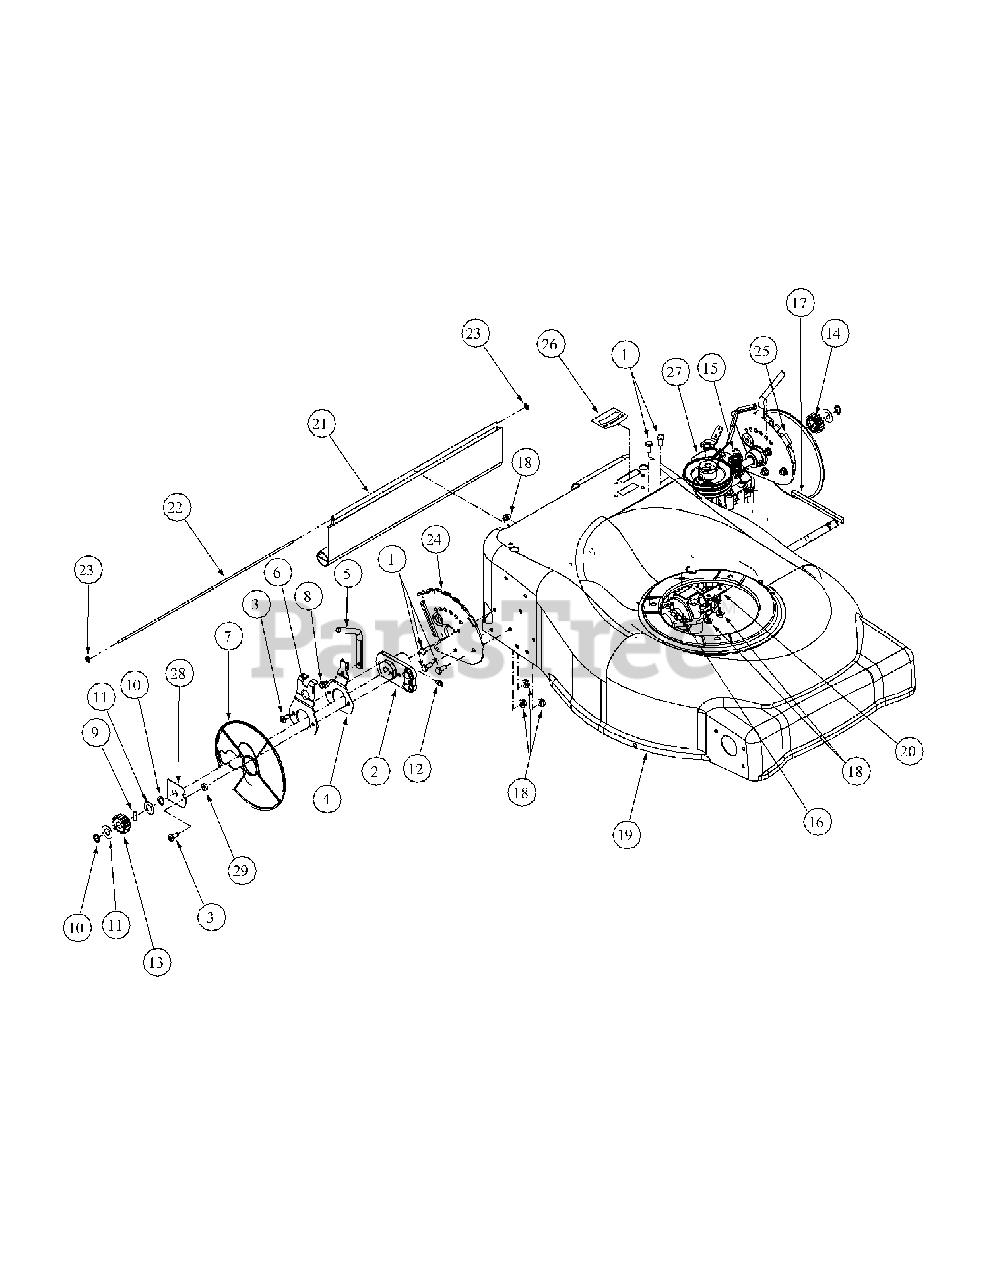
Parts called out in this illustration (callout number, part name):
1	Hex, Cap Screw, 1/4-20, .620
2	Pivot, Wheel, Bracket Assembly, 2 Pos
3	Screw, TT, 1/4-20, x .625
4	Height Adjuster, Spring Plate
5	Height Adjuster, Handle
6	Spring Lever, Support, Bracket
7	Drive Wheel, Dust, Cover
8	Screw, 1/4-20, x .375, Index Washer
9	Dowel Pin, 3/16 x 3/4
10	Retainer Ring, .500 Dia Heavy Duty
11	Flat Washer, .508 ID x 1.00 OD x .020
12	Grease Fitting
13	Pinion Gear, 15T, With Ratchet, R
14	Pinion Gear, 15T, With Ratchet, L
15	Extension Spring, .75 OD x 2.37
16	Belt, Pin, Keeper
17	Belt, V Type, 3/8 x 32.92 Long
18	Nut, 1/4-20, Hex Flange, Lock
20	Transmission, Spring Bracket, Tuff Torque
21	Trail Shield
22	Shield Rod
23	Push On, 4MM
24	Right Rear, Height Adjustment Bracket
25	Left Rear, Height Adjustment Bracket
26	Label, 21" Deck Shift
27	3-Speed Transmission
28	21" Dust Cover Support
29	Dust Cover Spacer
